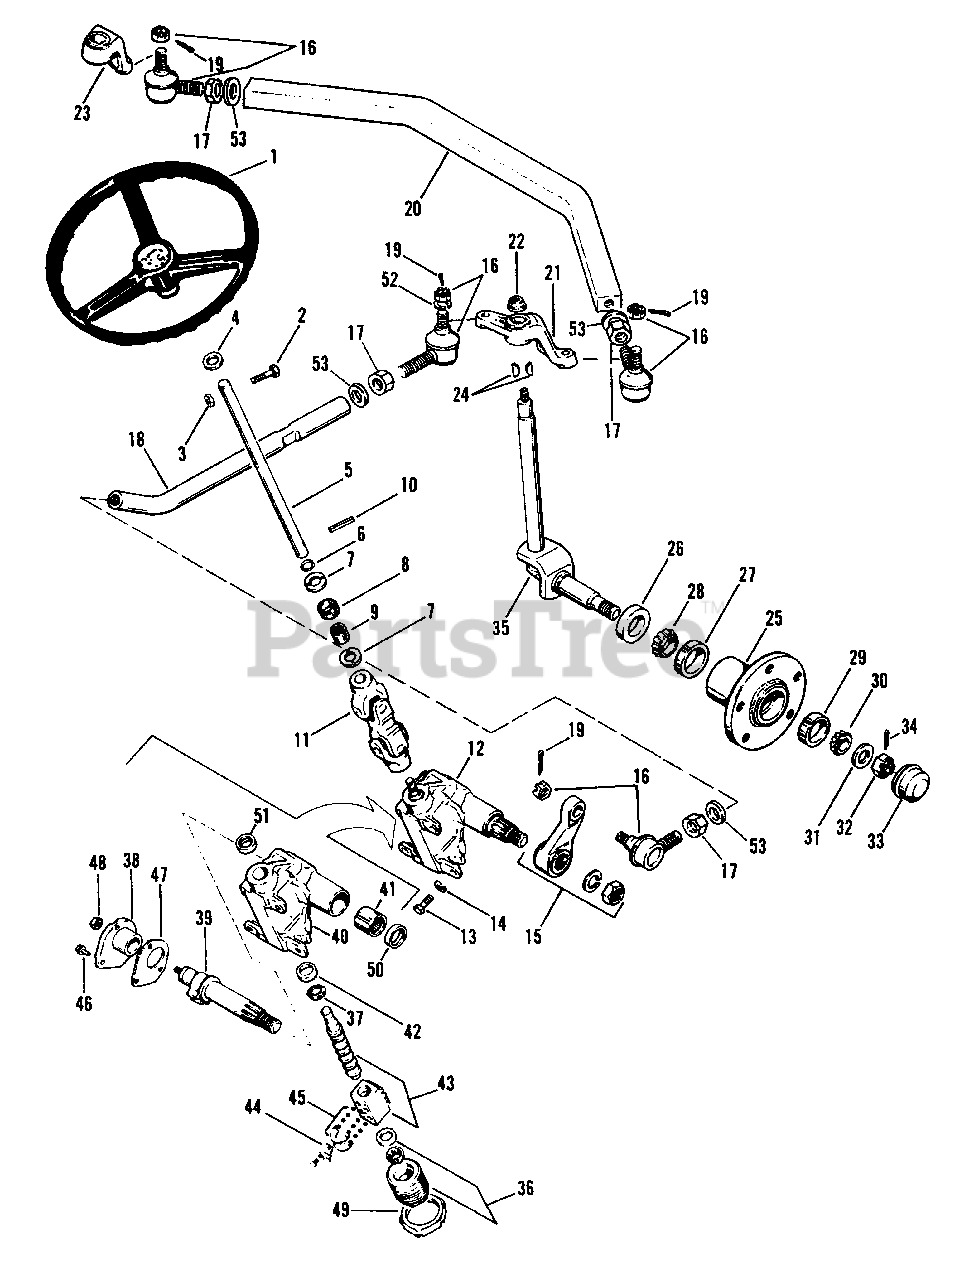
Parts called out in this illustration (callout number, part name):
1	Steering Wheel
2	Hex Capscrew, 5/16"-18 x 1-1/4" lg.
3	Hex Lock Nut, 5/16"-18
5	Steering Shaft
6	Retaining Ring
7	Thrust Washer
8	Roller Bearing
9	Needle Bearing
10	Roll Pink 3/8" x 1-1/4" lg.
11	"U" Joint
12	Steering Gear Complete
13	Hex Capscrew, 7/16"-14 x 1" lg.
14	Lockwasher, 7/16"
15	Pitman Arm
17	Hex Jam Nut
18	Drag Link
19	Cotter Pin
21	Steering Arm, Right Hand
22	Washer Base Lock Nut
23	Steering Arm, Left Hand
25	Hub Assy. (Mfg. No. 920) (Incl. Ref. Nos. 26, 27, 28 & 29)
25	Hub Assy. (Mfg. Nos. 953 & 954) (Incl. Ref. Nos. 26, 27, 28 & 29)
27	Bearing Cup
28	Bearing Cone
29	Bearing Cup
30	Bearing Cone (Mfg. No. 920)
30	Bearing Cone (Mfg. Nos. 953 & 954)
31	Thrust Washer
32	Slotted Nut
33	Hub Cap (Mfg. No. 920)
33	Hub Cap (Mfg. Nos. 953 & 954)
34	Cotter Pin
35	Spindle Assembly (Mfg. No. 920)
35	Spindle Assembly (Mfg. Nos. 953 & 954)
36	Worm Bearing Adj. Assy.
37	Worm Bearing Assembly
38	Cover Assembly
39	Pitman Gear Assembly
40	Housing Assembly
41	Needle Bearing
42	Bearing Thrust Cup
43	Worm Assembly
44	Ball Return Clamp
45	Ball Return Guide
50	Grease Seal
52	Lockwasher, 1/2"
